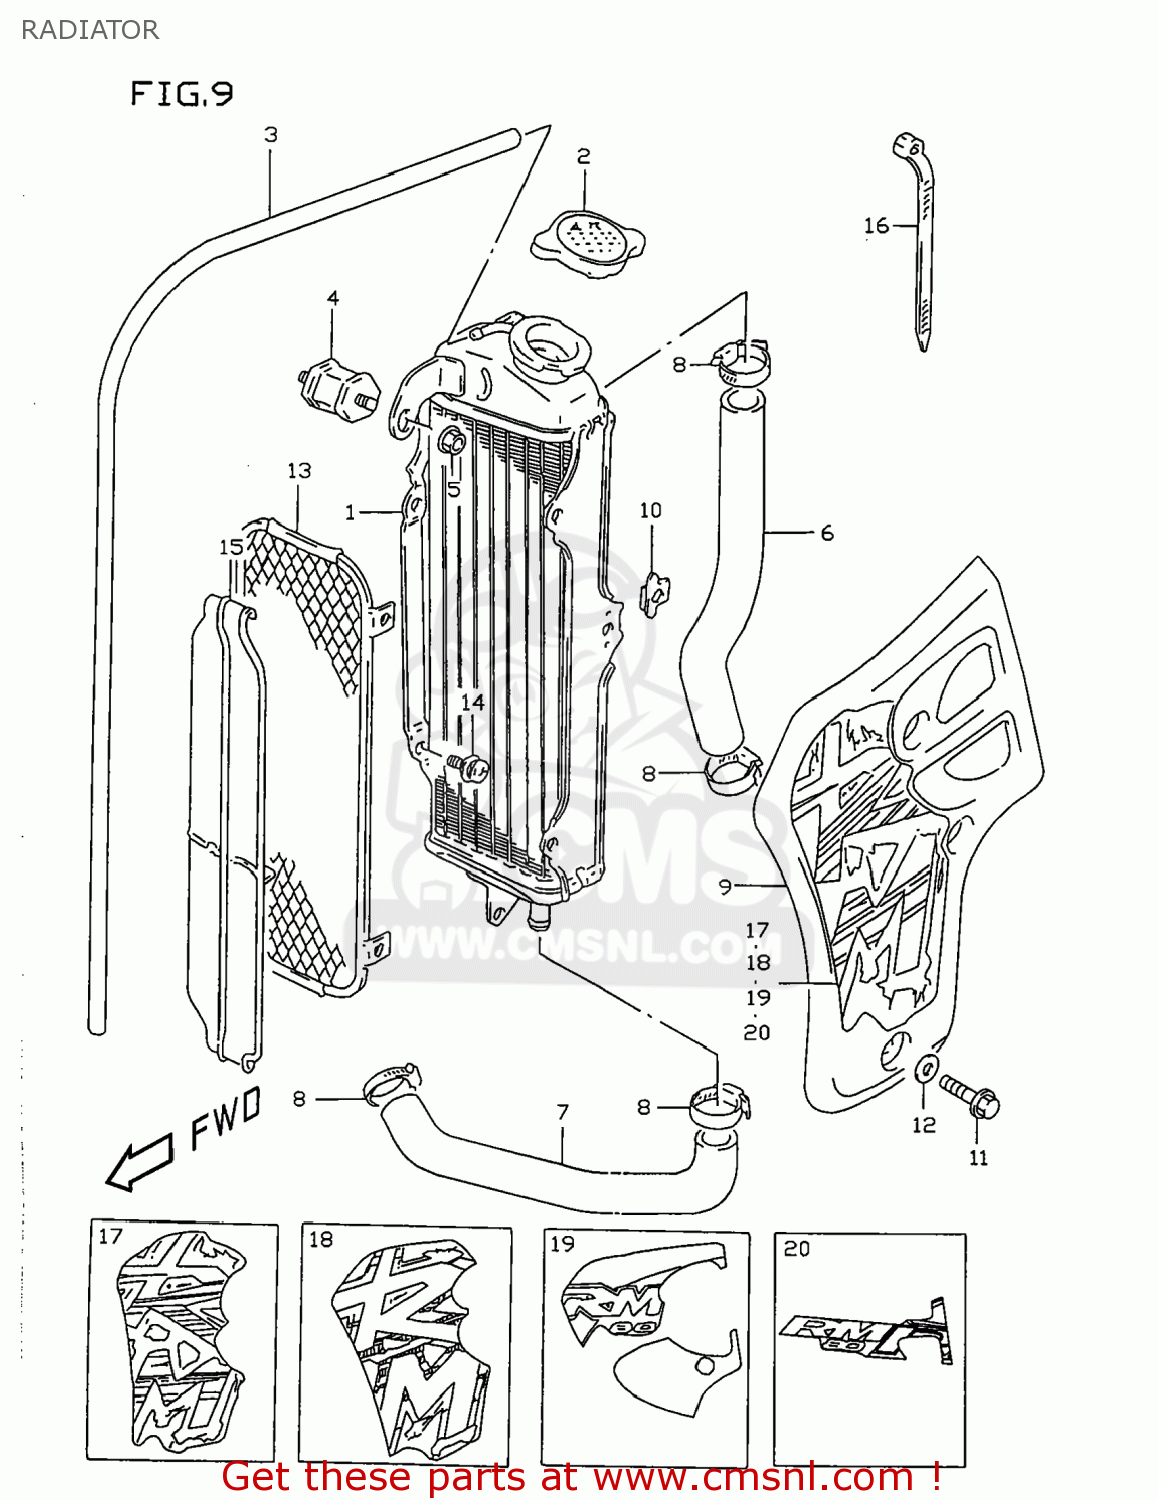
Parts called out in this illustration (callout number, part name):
1	RADIATOR COMP,WATER
2	CAP,RADIATOR
3	HOSE (5X8X600)
4	BOLT,RADIATOR CUSHION
5	NUT
6	HOSE,RADIATOR INLET
7	HOSE,RADIATOR OUTLET
8	CLAMP
9	COVER,RADIATOR
10	PLATE,RADIATOR COVER FITING
11	BOLT
12	WASHER(6.5X18X1)
13	BUMPER,RADIATOR
14	SCREW
15	COVER,RADIATOR
16	CLAMP(L:235)
17	EMBLEM,RADIATOR COVER
18	EMBLEM,RADIATOR COVER
19	TAPE SET,RADIATOR COVER
20	TAPE,RADIATOR COVER
